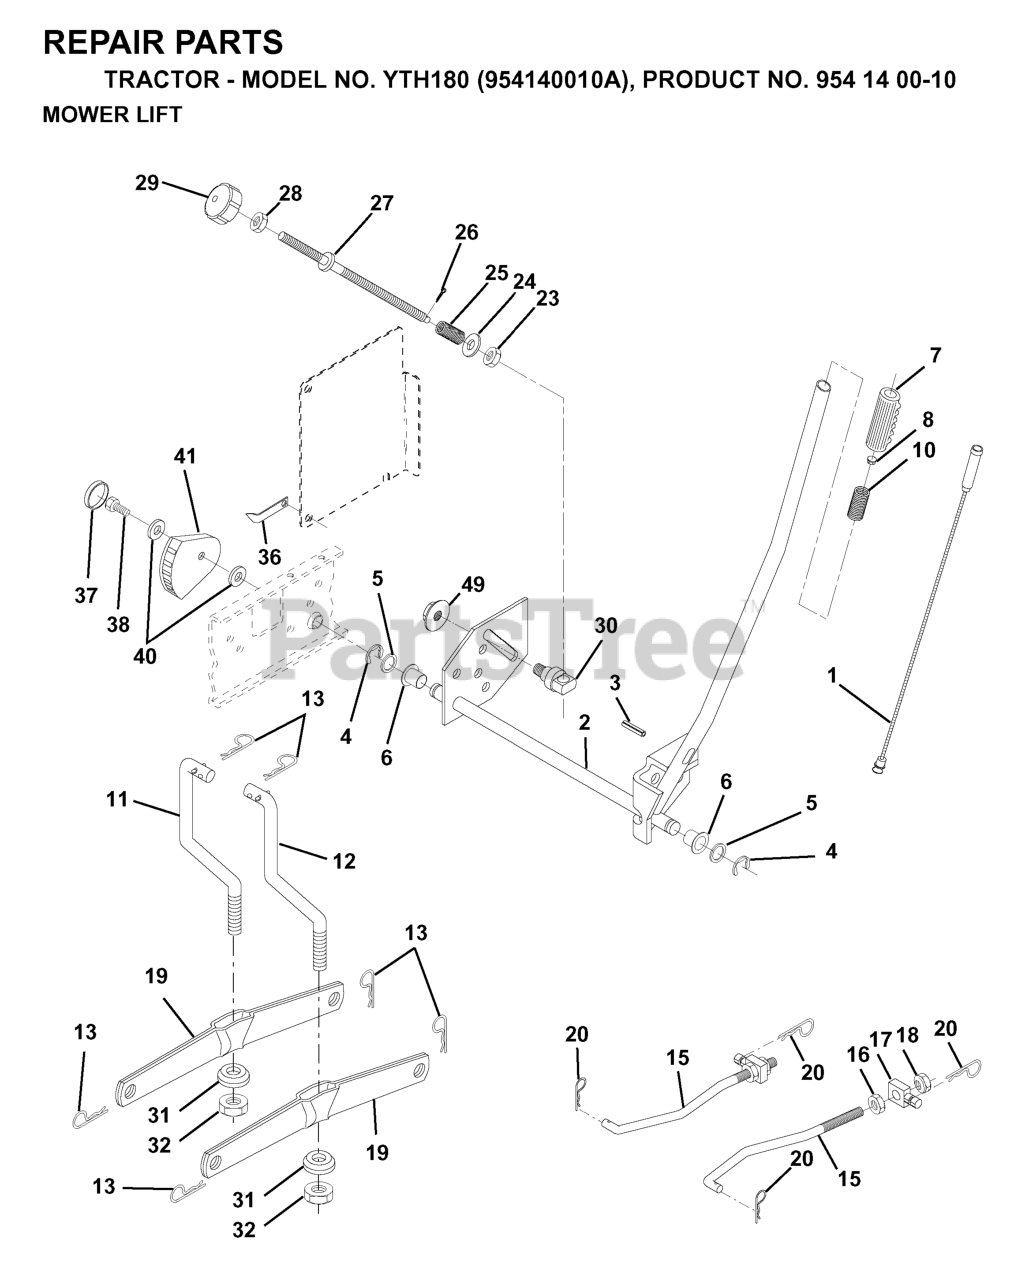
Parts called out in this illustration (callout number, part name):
1	WIRE.INNER.HANDLE.LIFT.LEVER
2	SHAFT ARM LIFT RH
3	PIN GROOVE.
4	RETAINING RING LT
6	BEARING.NYLON
7	GRIP HANDLE
8	PLUNGER BUT KIT
10	SPRING, COMP T
11	LINK LIFT LH
12	LINK LIFT RH
13	RETAINER-SPRNG RB
15	FRONT LINK
16	NUT.HEX.JAM.1/2-13
17	TRUNION
18	NUT.LK.W/WSH.1/2.
19	ARM.REAR.SUSPENSION
20	SPRING RETAINER
25	SPRING**
26	COTTER PIN
27	ROD ADJ LIFT
28	NUT
29	KNOB INF 3/8-16
31	BEARING PIVOT
32	NUT CROWNLOCK 3/8-24
36	POINTER, HEIGHT INDICATOR(2 2)
38	SCREW.THDROL.5/16-18X3/4.TTY
41	IND. HEIGHT STLT
49	NUT
